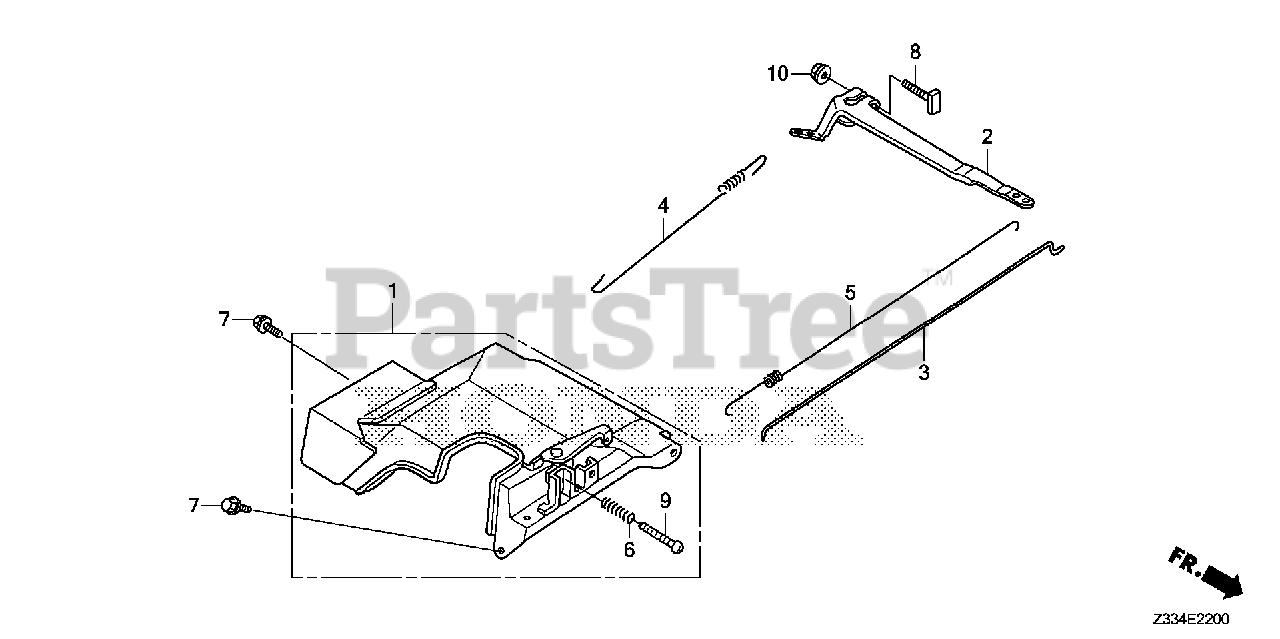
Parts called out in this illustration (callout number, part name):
1	CONTROL ASSY.
1	CONTROL ASSY. (COO)(FOR U.S.A.)
2	ARM, GOVERNOR
3	ROD, GOVERNOR
4	SPRING, GOVERNOR
5	SPRING, THROTTLE RETURN
6	SPRING, CONTROL ADJUSTING
7	BOLT, FLANGE (6X12) (CT200)
8	BOLT, GOVERNOR ARM
9	SCREW, PAN (5X35)
10	NUT, FLANGE (6MM)
